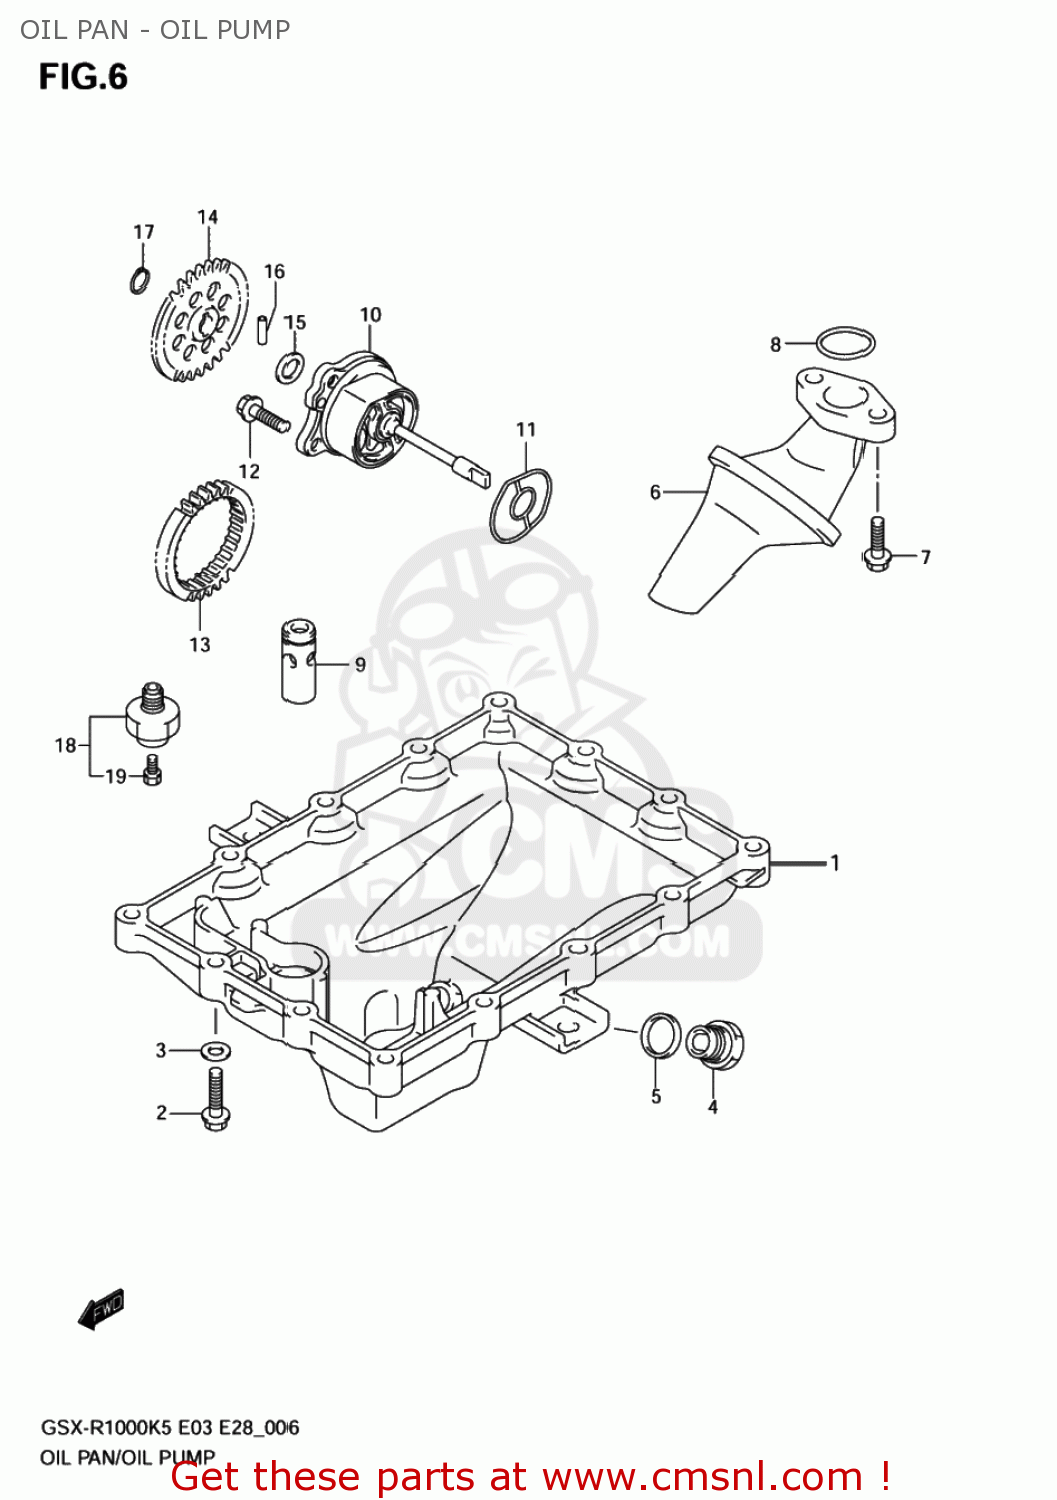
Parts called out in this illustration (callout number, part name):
1	PAN,OIL
2	SCREW
3	GASKET(5.8X13X1.2) (NAS)
4	PLUG(14X20)
5	GASKET(13.8X18.8X4.8) (NAS)
6	STRAINER ASSY,ENGINE OIL
7	BOLT
8	O RING(D:2.62,ID:20.3)
9	VALVE ASSY,OIL RELIEF(7K)
10	PUMP ASSY,ENGINE OIL
11	O RING,OIL PUMP
12	SCREW
13	GEAR,OIL PUMP DRIVE
14	GEAR,OIL PUMP DRIVEN
15	SHIM(10X18X0.5)
16	PIN(4X15.8)
17	CIRCLIP,10MM
18	SWITCH ASSY,OIL PRESSURE
19	BOLT,OIL PRESSURE SWITCH
